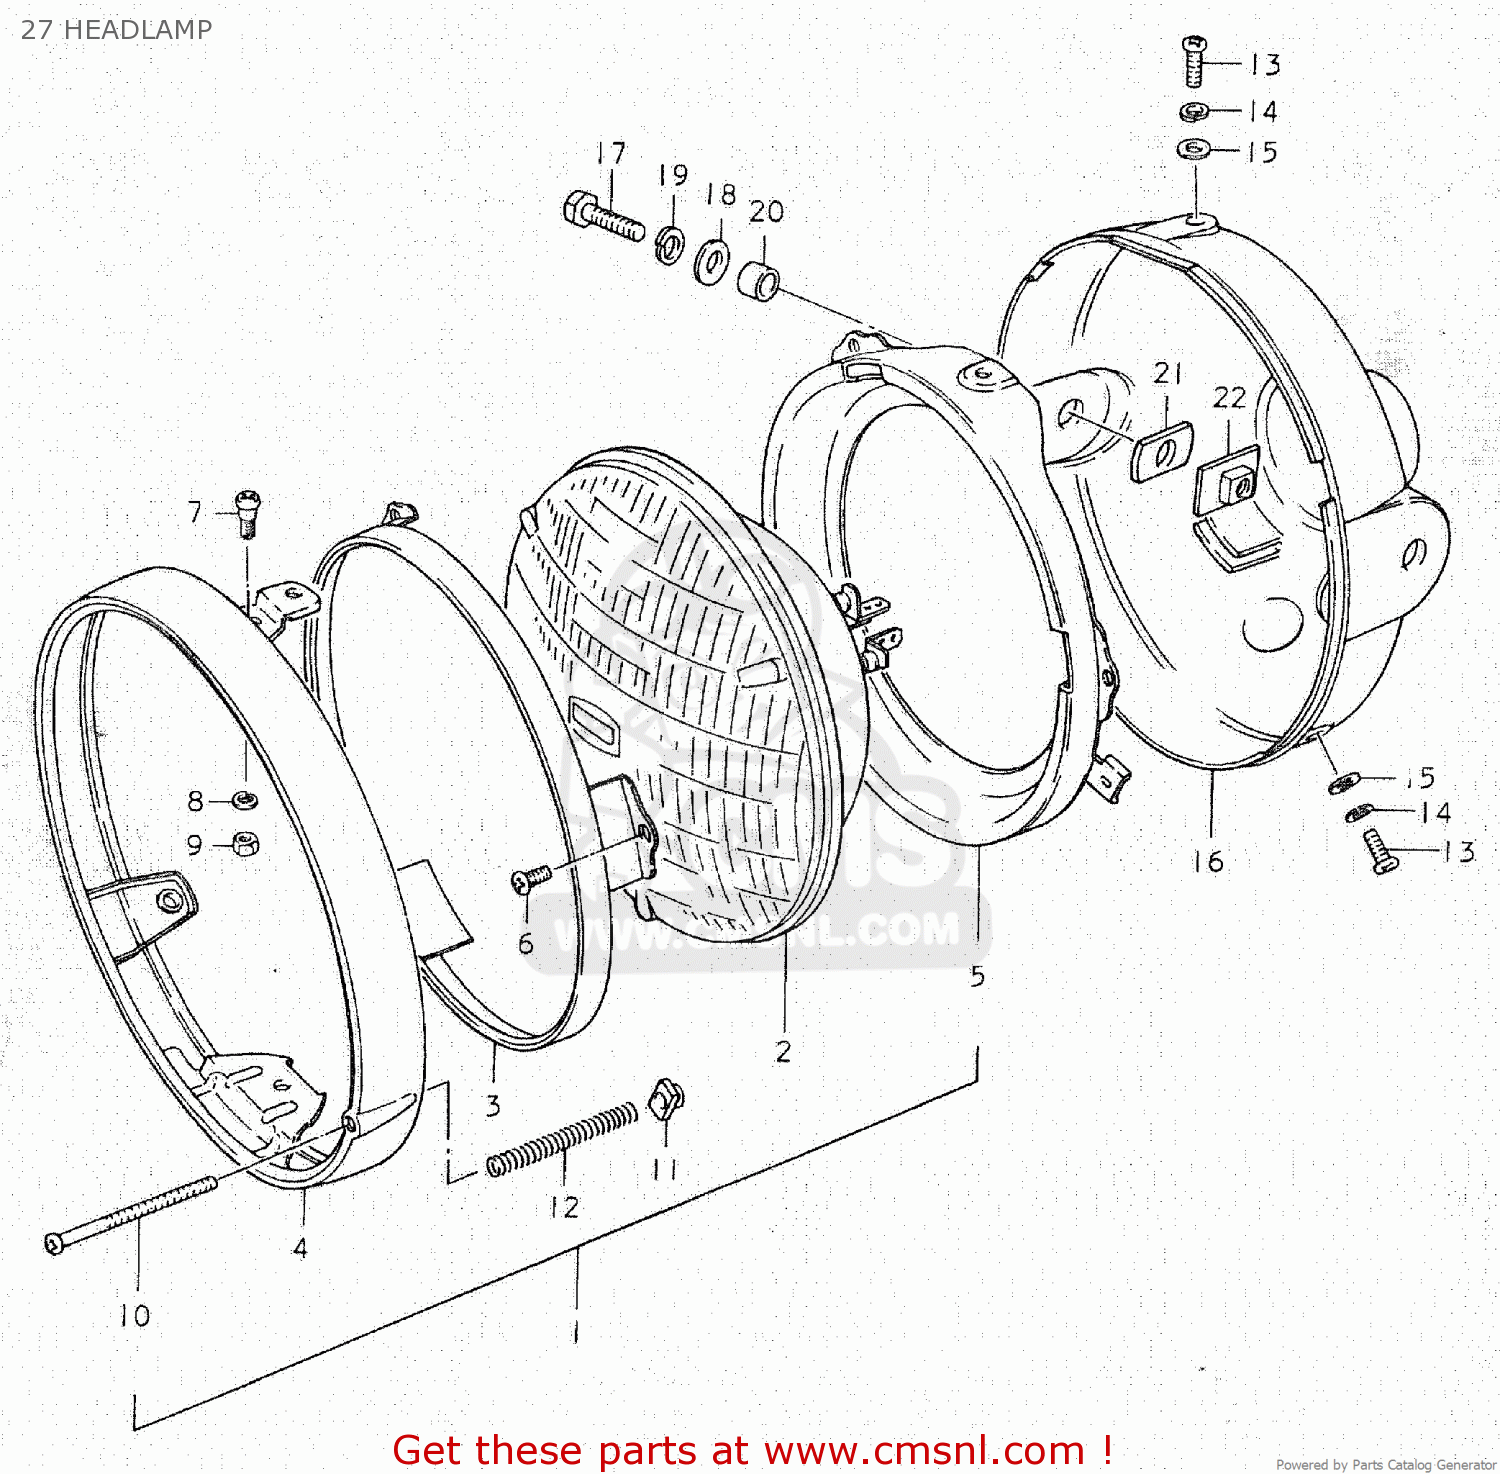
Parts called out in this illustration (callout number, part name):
1	HEADLAMP ASSY
2	UNIT
3	RETAINING RING
4	RIM
5	RING
6	SCREW
7	H/LAMP LENS UNIT FITING SCRE
8	LOCK WASHER
9	NUT
10	SCREW,HEADLAMP ADJUST
11	NUT
12	SPRING,ADJUSTING
13	SCREW
14	WASHER,LOCK
15	WASHER
16	HOUSING,HEADLAMP(BLACK)
17	BOLT
18	WASHER
19	LOCK WASHER
20	SPACER (8.8X12X7)
21	CUSHION
22	PLATE,HEADLAMP HOUSING
